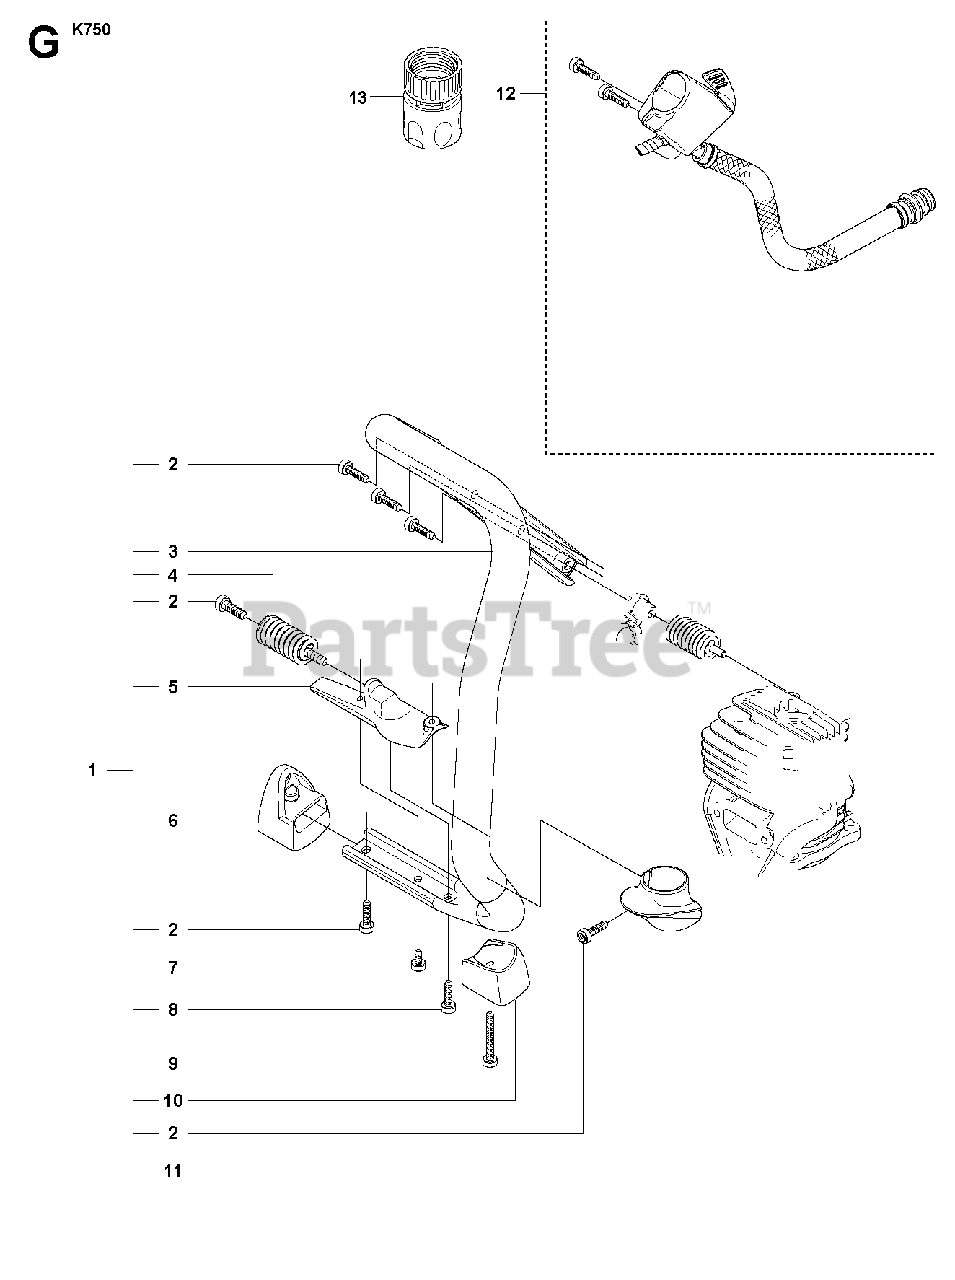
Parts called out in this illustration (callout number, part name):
1	HANDLEIncl. 2 - 12
2	SCREW ITXSCM
3	FRONT HANDLE
4	ANTIVIBRATION ELEMENT
5	SPRING RETAINER
6	GROUND SUPPORT
7	SCREW ITXSCM
8	SCREW ITXSCM
9	SCREW ITXSCM
10	GROUND SUPPORT
12	HOSE ASSY
